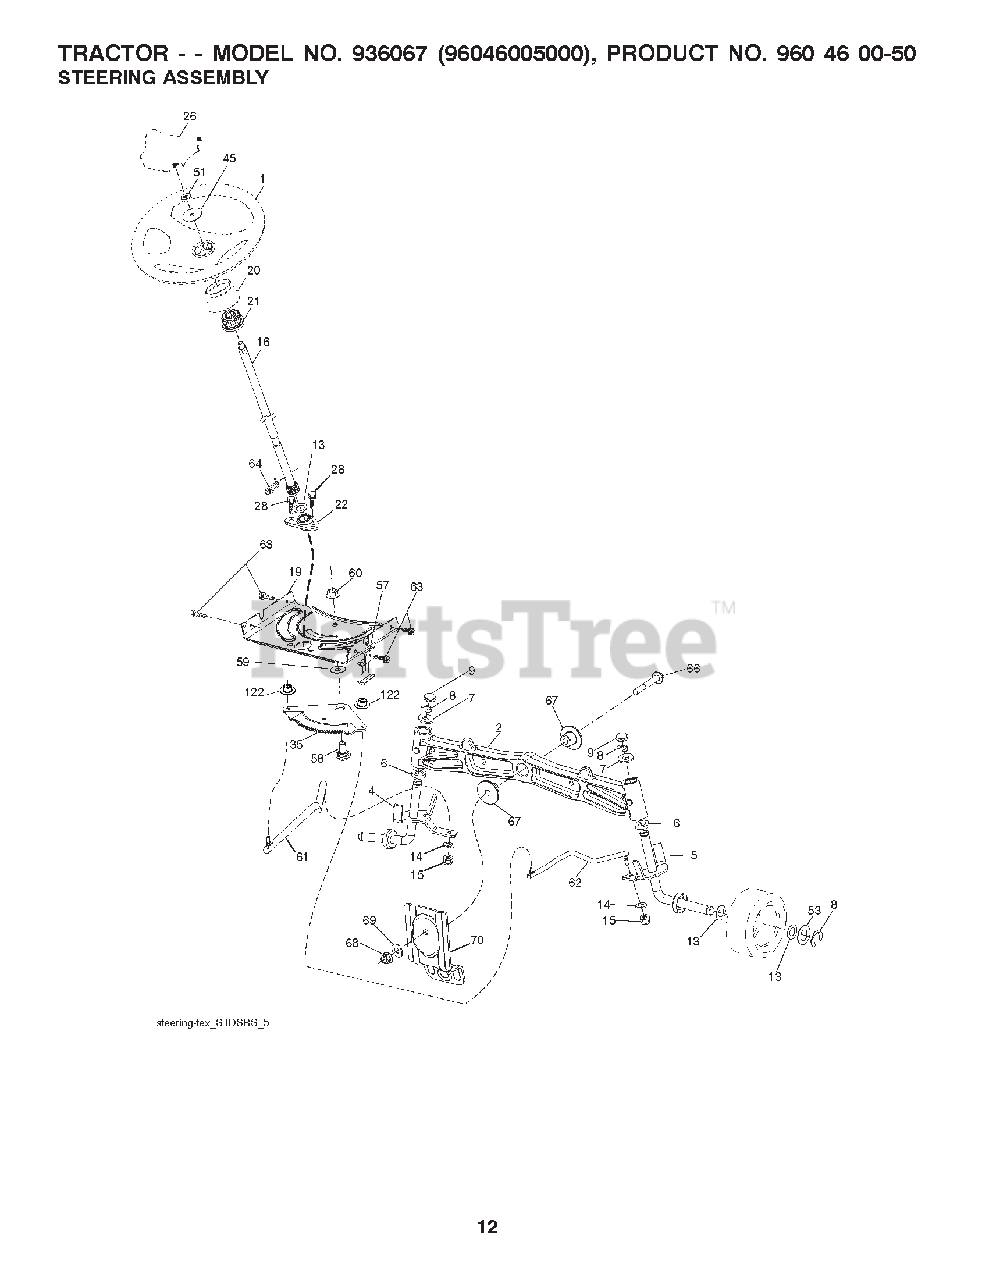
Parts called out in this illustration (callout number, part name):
1	WHEEL STEERING
2	AXLE.CAST IRON
4	SPINDLE.WELDED.LH.15"TEX
5	SPINDLE.WELDED.RH.15"TEX
6	WAHSER THRUST .75 X 1.230
7	WASHER.25/32 X 1-5/8 X 16GA.
8	RING.KLIP.#T5304-75
9	CAP.SPINDLE.FR.TOP.BLK.
13	WASHER.25/32 X 1 1/4 X 16 GA.
14	Washer, Lock 3/8
15	NUT.CROWNLOCK.3/8-24
16	SHAFT.STEER.3/4 TEX.NON-PLATED
19	PLATE.STEER.DDL.NLT/NGT
20	BOOT.STEERING
21	ADAPTER.WHEEL.STRG..760
22	STEERING SUPT. LOWER
26	CAP WHEEL STEERING HRS/SRS BLK
28	SCREW.HEXWSH THDR3/8-16X3/4.BL
35	GEAR SECTOR.PLATE.DDL.NLT/NGT
45	WASHER.11/32ID X2 3/8OD X 12GA
51	NUT.HEX.JAM.TOPLOCK.1/2-20 UNF
53	WASHER.HARDEN..793 X 1.637X060
57	BRACKET.UPSTOP.GT/LT.TEX
58	BOLT.SHOULDER.SECTOR.PIVOT.CFM
59	WASHER.THRUST.SECTOR.STEER.NLT
60	NUT.FLANGE LOCK.5/8-11
61	DRAGLINK.LH.BALLSTUD.DDL.
62	DRAGLINK.RH.BALLSTUD.DDL
63	SCREW.5/16-18X3/4.SMGML.TAP/BL
64	RETAINER.CLIP.SPRING.STEERING
66	BOLT.HEX.FGHD.7/16-14 X 3.SERR
67	BUSHING.PM.FRONT AXLE
68	NUT.LOCK.FLANGE.7/16-14.GR5
69	WASHER.1.5 X .505 X .118
70	BRACKET.DECK.SUSPENSION.FRONT
122	CAP GEAR SECTOR
